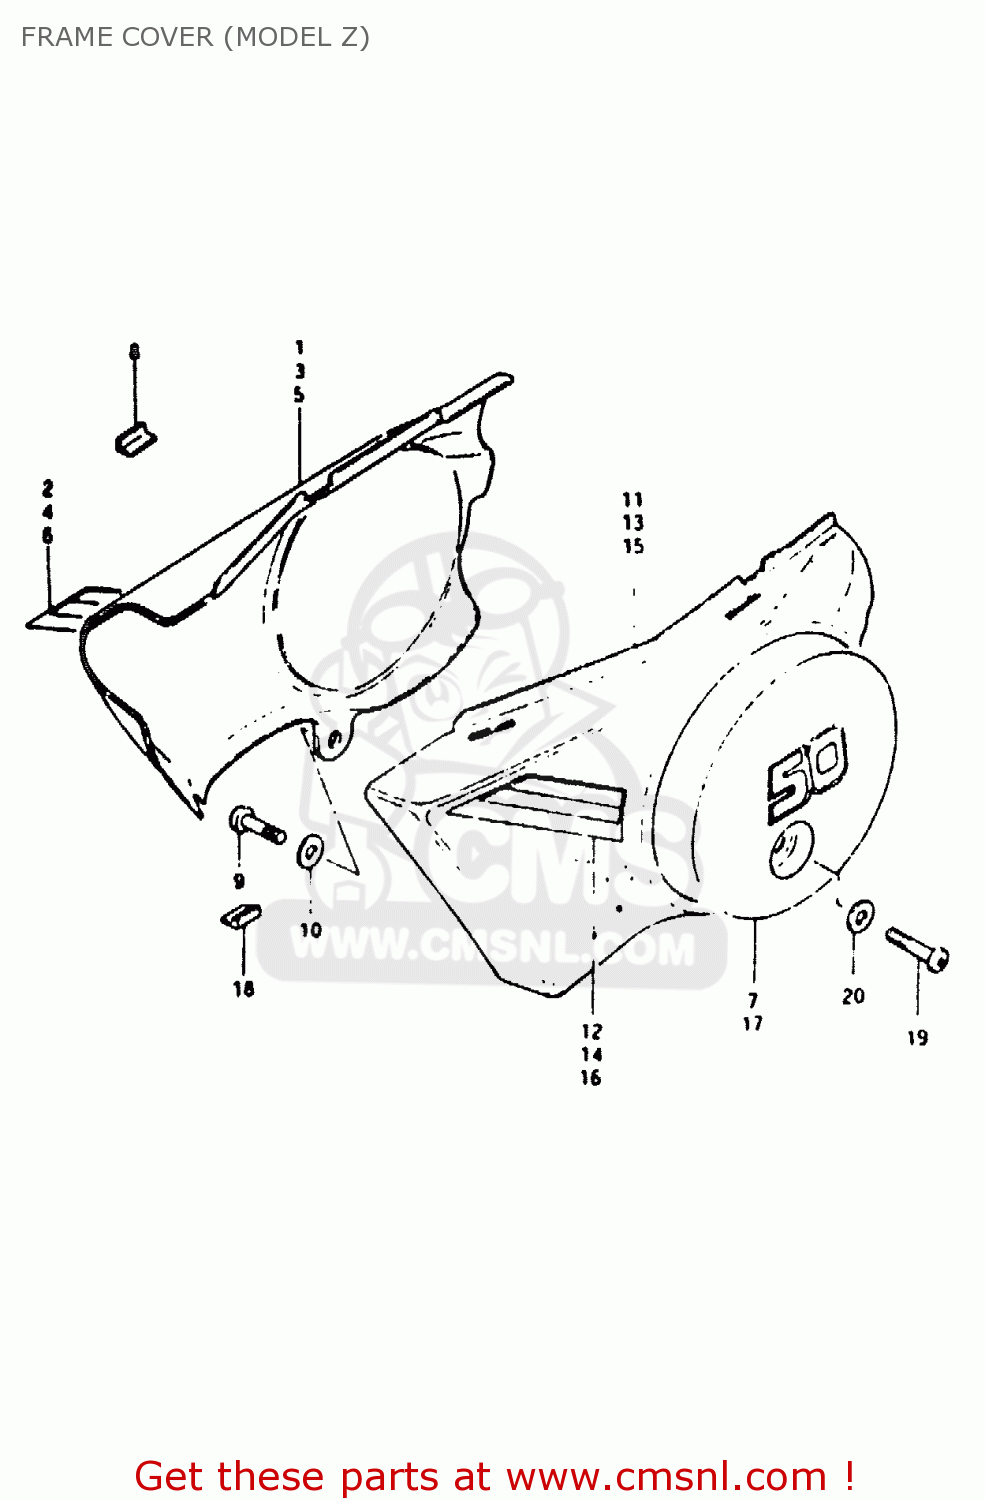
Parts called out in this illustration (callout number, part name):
1	COVER, FRAME RH (RED)
2	TAPE, STRIPING RH
3	COVER,FRAME RH
4	TAPE, RH
5	COVER,FRAME RH
6	TAPE, RH
7	EMBLEM, RH (WHITE)
8	CUSHION,FRAME COVER
9	SCREW
10	WASHER
11	COVER, FRAME LH (RED)
12	TAPE, LH
13	COVER, FRAME LH (BLUE)
14	TAPE, LH
15	COVER, FRAME LH (YELLW)
16	TAPE, LH
17	EMBLEM, LH (WHITE)
18	CUSHION,FRAME COVER
19	SCREW
20	WASHER
